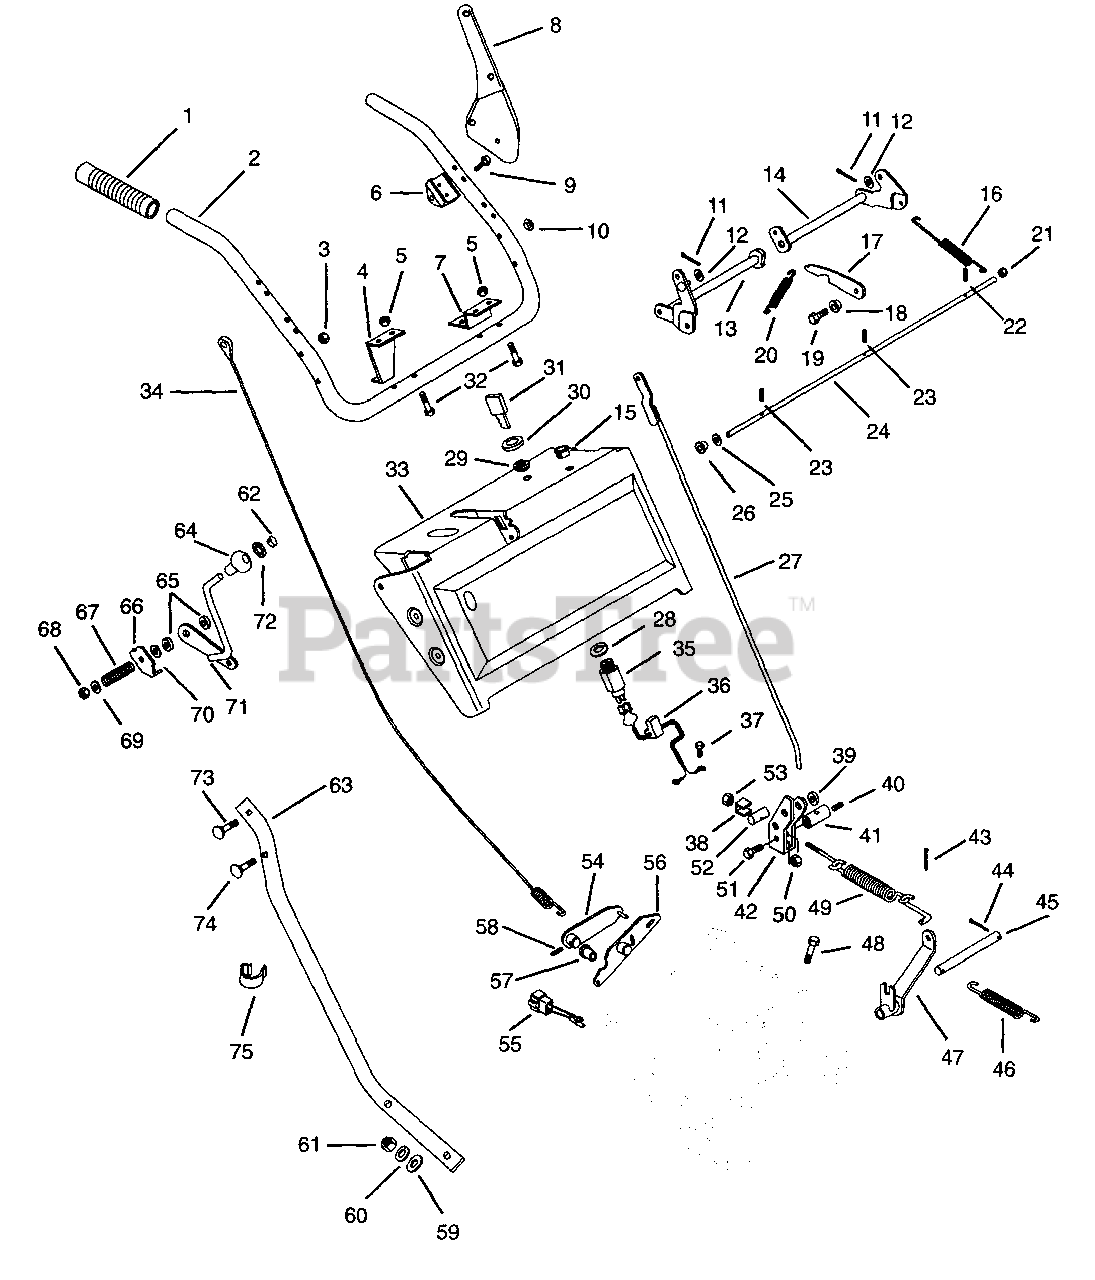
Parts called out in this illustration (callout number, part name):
1	HANDLE GRIP
2	UPPER HANDLEBAR
3	@NUT-SPNLK-FLG .312-18 YWZC
4	BRACKET, ROD
5	@NUT-LK-CTR .25-20 YWZC
6	HANDLE PIVOT
7	BRACKET, CHUTE CRANK
8	CLUTCH LEVER - COATED
9	SCR-TAP 12-24X1.50 CROVH YZ BT
11	PIN COTR .09X.50 PL
12	WSHR-FL-STL .268X.562X.046 PL
13	RH LEVER
14	LH LEVER
15	SNAP BUSHING
16	SG-TENS .051X.50X5.12 WLD 10.4
17	ARM, LATCH
18	BSHG-FLG .265X.437X.329X1.00
19	@BLT-HEX .25-20X.75 GR5 YWZC
20	SG-TENS .048X.44X1.75 WLD 9
21	NUT-CROWN .312-18 YWZC
22	PIN-ROLL .156X.75
23	PIN-ROLL .125X1.00
25	@WSHR-FL-STL.344X.688X.065YWZC
26	BSHG-FLG .325X.465X.333X.685
27	TRACTION CLUTCH ROD
28	WSHR-LK-INT .625X.045 YWZC
29	NUT-PANEL .625-32 GRECO
30	CAP - IGNITION SWITCH
31	KEY -W/CAP
32	BLT-HEX .25-20X1.25 PL GR5
33	PANEL W/DECAL
34	CABLE, BLOWER CLUTCH
35	SWITCH ASSEMBLY
36	SHORTING WIRE
36	ST 12V HARNESS
37	SCR-TAP .250-20X.37 HWH PL TR
38	ADAPTER SPACER
39	SPACER 1.00 X .64 X .38
40	SCR-SET .32-18X.38 SKHCUPNL OH
41	ROD ADAPTER
42	CLUTCH ENGAGEMENT YOKE
43	@PIN-CTR .09X.50 EXTPRSQCT YWZ
44	@PIN-CTR .09X1.00 EXTPRSQCT YZ
45	ROD, FORK PIVOT
46	SG-TENS .080X.73X3.06 WLD 20
47	FORK, CLUTCH
48	BLT-HEX .375-16X1.0 YWZC
49	SPRING ASSEMBLY
50	@NUT-LK-CTR .31-18 YWZC
51	BLT-HEX .31-18X.750 YWZC
52	ADAPTER
53	@NUT-LK-NYL .312-18 YWZC
54	LEVER CLUTCH
55	JUMPER
57	BSHG-FLG.500X.625X.312X.750NY
58	PIN-ROLL .156X.88
59	@WSHR-FL-STL.312X.734X.065 YWZ
60	WSHR-LOCK .38X.094 REG YWZC
61	@NUT-HEX .38-16 YWZC
62	HOLE PLUG
63	L H LOWER HANDLEBAR
63	R H LOWER HANDLEBAR
64	KNOB
65	FRICTION WASHER
66	PRESSURE FLANGE
67	SG-COMP .187X.56X1.62
68	@NUT-LK-CTR .38-16 YWZC
69	@WSHR-FL-STL.406X.812X.065 YWZ
70	SPACER .406X.620X.125
71	LEVER-DEFLECTOR
72	RG-RTNG-EXT .375X.010
73	@BLT-RDHDSQNK .31-18X1.75 G5YZ
74	BLT-RDHDSQNK .31-18X2.75 SHPL
